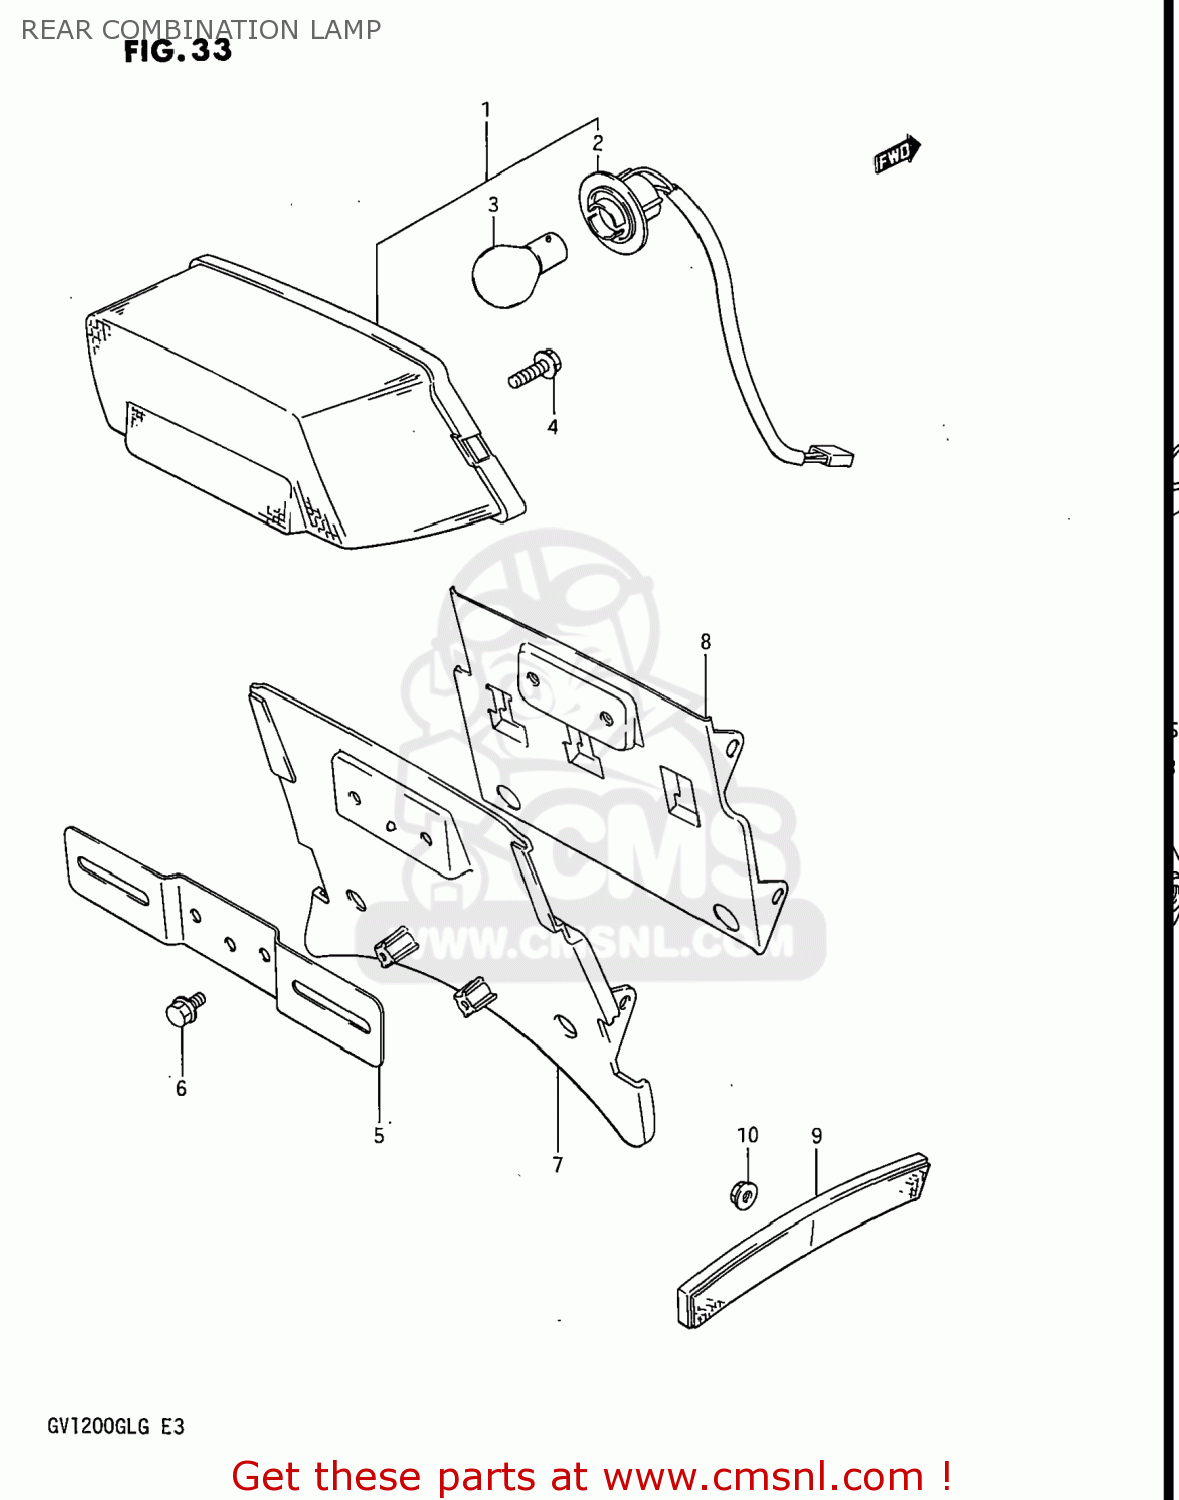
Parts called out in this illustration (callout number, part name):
1	LAMP ASSY,RR COMBINATION
2	SOCKET & CORD ASSEMBLY
3	BULB(12V23/8W,TOKAI DENSO)
4	BOLT
5	PLATE,RR LICENSE
6	BOLT 6X12
7	COVER,LICENSE PLATE
8	REINFORCEMENT,REAR COVER
9	REFLECTOR,REFLEX
10	NUT
